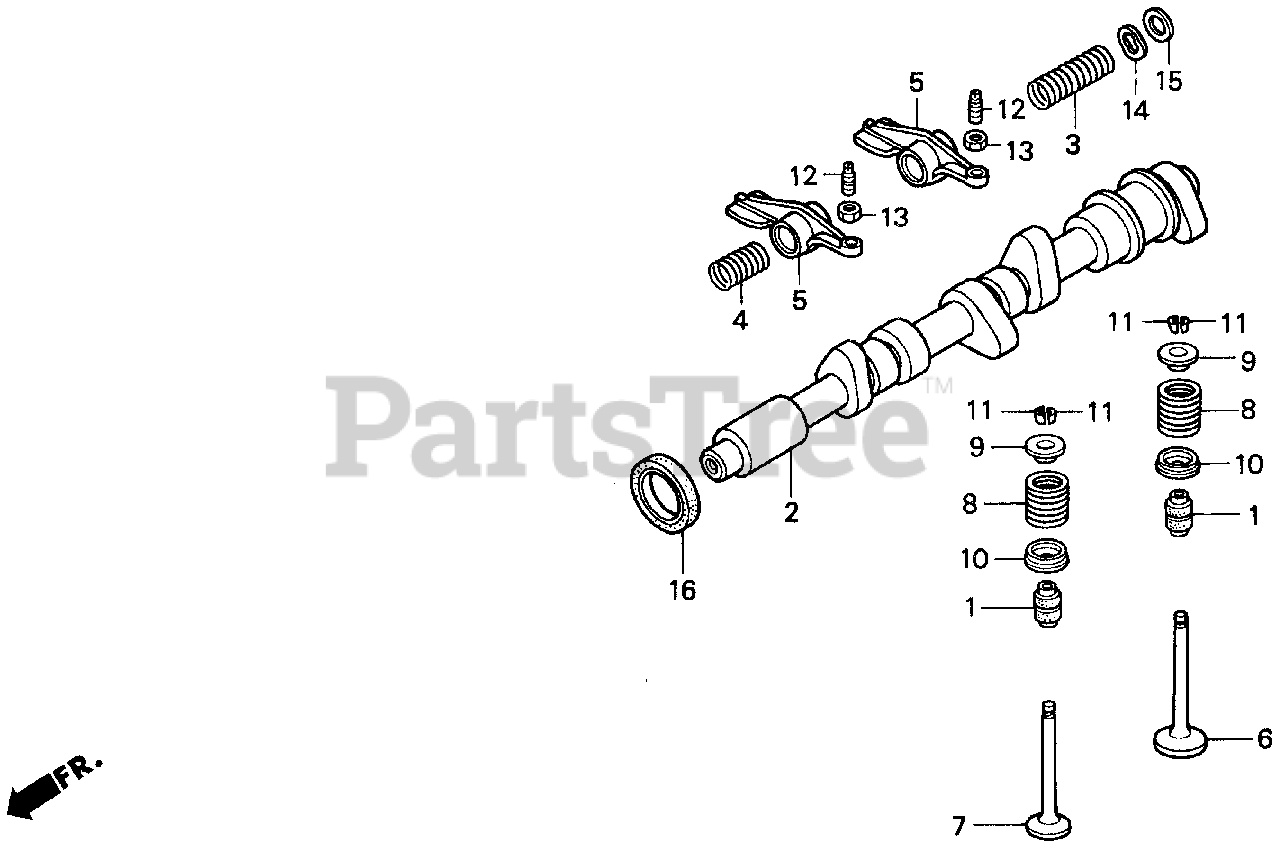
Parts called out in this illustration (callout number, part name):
1	SEAL, VALVE STEM
3	SPRING, ROCKER ARM A SHAFT
4	SPRING, ROCKER ARM B SHAFT
5	ARM, ROCKER
6	VALVE, IN.
7	VALVE, EX.
8	SPRING, VALVE
9	RETAINER, VALVE SPRING
10	SEAT, VALVE SPRING
11	COTTER, VALVE (FUJI VALVE)
12	SCREW, TAPPET ADJUSTING
13	NUT, TAPPET ADJ.
14	WASHER, WAVE
15	WASHER, THRUST (16MM)
16	OIL SEAL (29X45X8)
